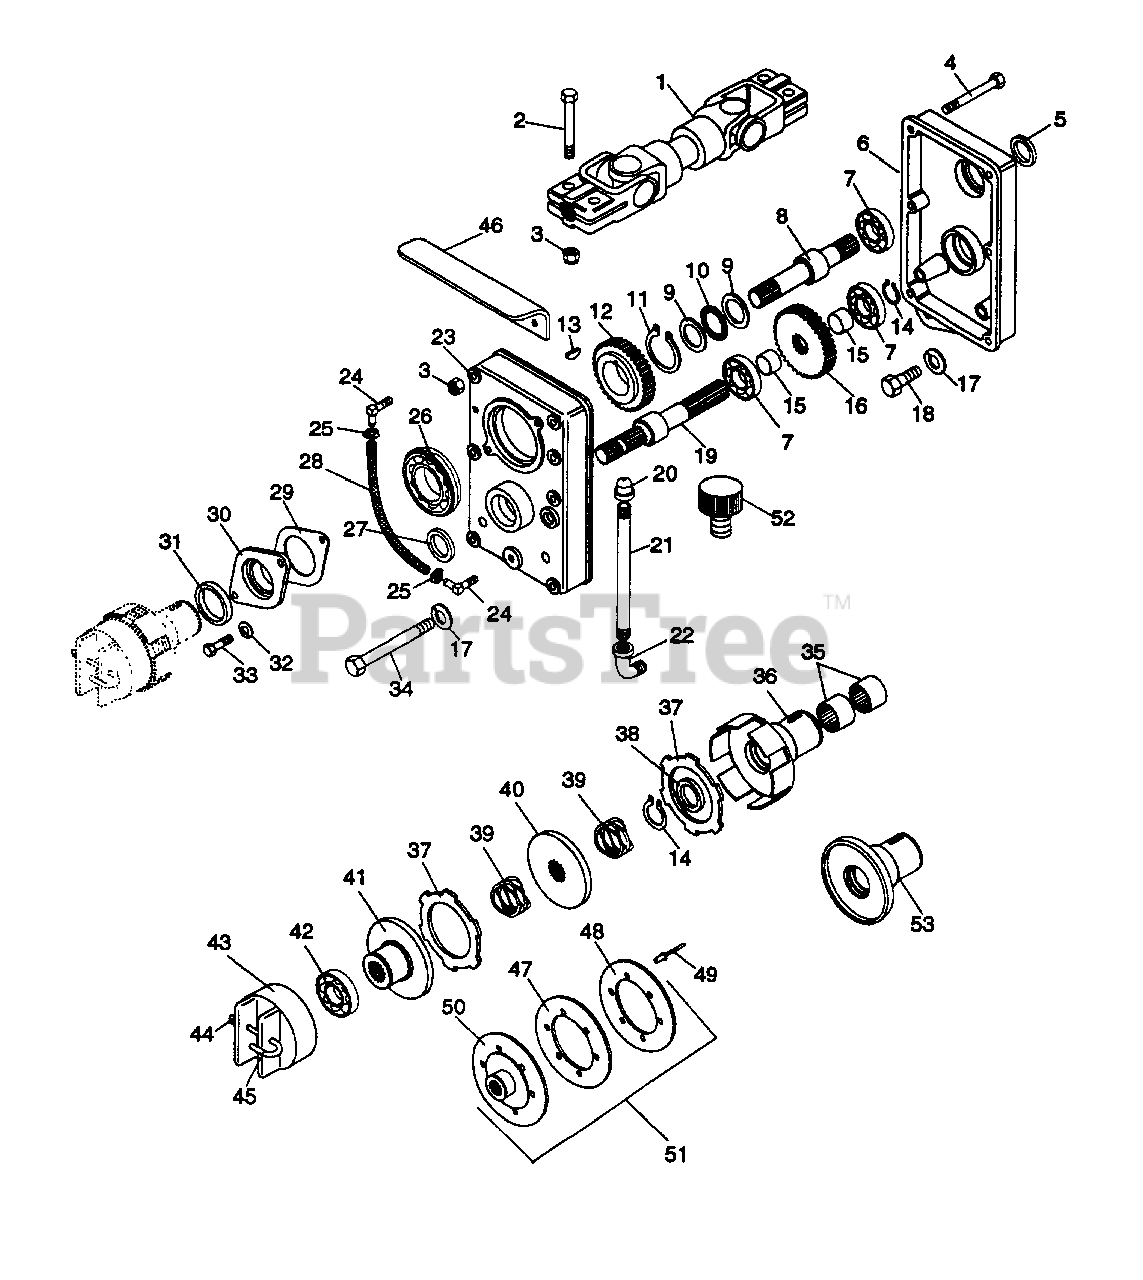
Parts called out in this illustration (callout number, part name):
1	ASM, PTO U-JOINT
2	BLT-HEX .38-16 X 1.75 PL GR 5
3	NUT-LK-NYL .375-16 PL
4	BLT-HEX .38-16 X 3.50 PL GR 5
5	SEAL-LIP .984 X 1.6 X .25
6	CASE, PTO
7	BRG-BALL .984 X 2.047 X .591
8	SHFT, PTO INPUT
9	WSHR-THRST 1.55 X 1.002 X .093
10	BRG-N-THRST 1.0 X 1.55 X .078
11	RG-RTNG-EXT 1.819 X .062
12	GR, PTO INPUT 10DP 41T
13	KEY, WDRF 1/4 X 1 HRD # 15
14	RG-RTNG-EXT .906 X .078
15	BUSH., S1.01 X 1.25 X .645 ST
16	GR, PTO OUTPUT 10DP 45T
17	WSHR-LOCK .50 REG.
18	BLT-HEX .50-13 X 1.50 PL GR 5
19	SHFT, PTO OUTPUT
20	CAP, PIPE 3/8
21	NIPPLE, PIPE .38 X 6.0 UNFIN STL
22	EL .38 X 90 STRT UNFIN MAL LR
24	EL, HOSE
25	HOSE CLAMP
26	BRG BALL 1.97 X 3.14 X .63
27	SEAL-LIP 1.25 X 1.75 X .25
28	HOSE, 1/4 IN VINYL
29	GSKT, FRT PTO CAP
30	CAP, FRONT PTO
31	SEAL 2.250 X 3.002 X .375
32	WSHR-LOCK .313 X .078 PL
33	BLT-HEX .31-18 X .75 PL GR 5
34	BLT-HEX .50-13 X 4.25
35	BRG-ROLLER 1.0 X 1.312 X .75
36	HUB, PTO CLUTCH
37	DISC, CLUTCH
38	SEAL-LIP 1.0 X 1.50 X .25
39	SPRG, WAVE
40	PLT, CLUTCH
41	HUB, CLUTCH ACTUATING
42	BRG-BALL 1.57 X 3.15 X .71
43	TRUNION, FWD-REV CLUTCH
44	PIN-COTR .062 X .75 PL
45	PIN, CLUTCH SPRING
46	GRD, CLUTCH
47	RING, CLUTCH
48	LNG, CLUTCH
49	RIVET, CLUTCH
50	HUB, PTO CLUTCH
51	DISC, PTO CLUTCH
52	CAP, FILTER
53	HUB, PTO CLUTCH
